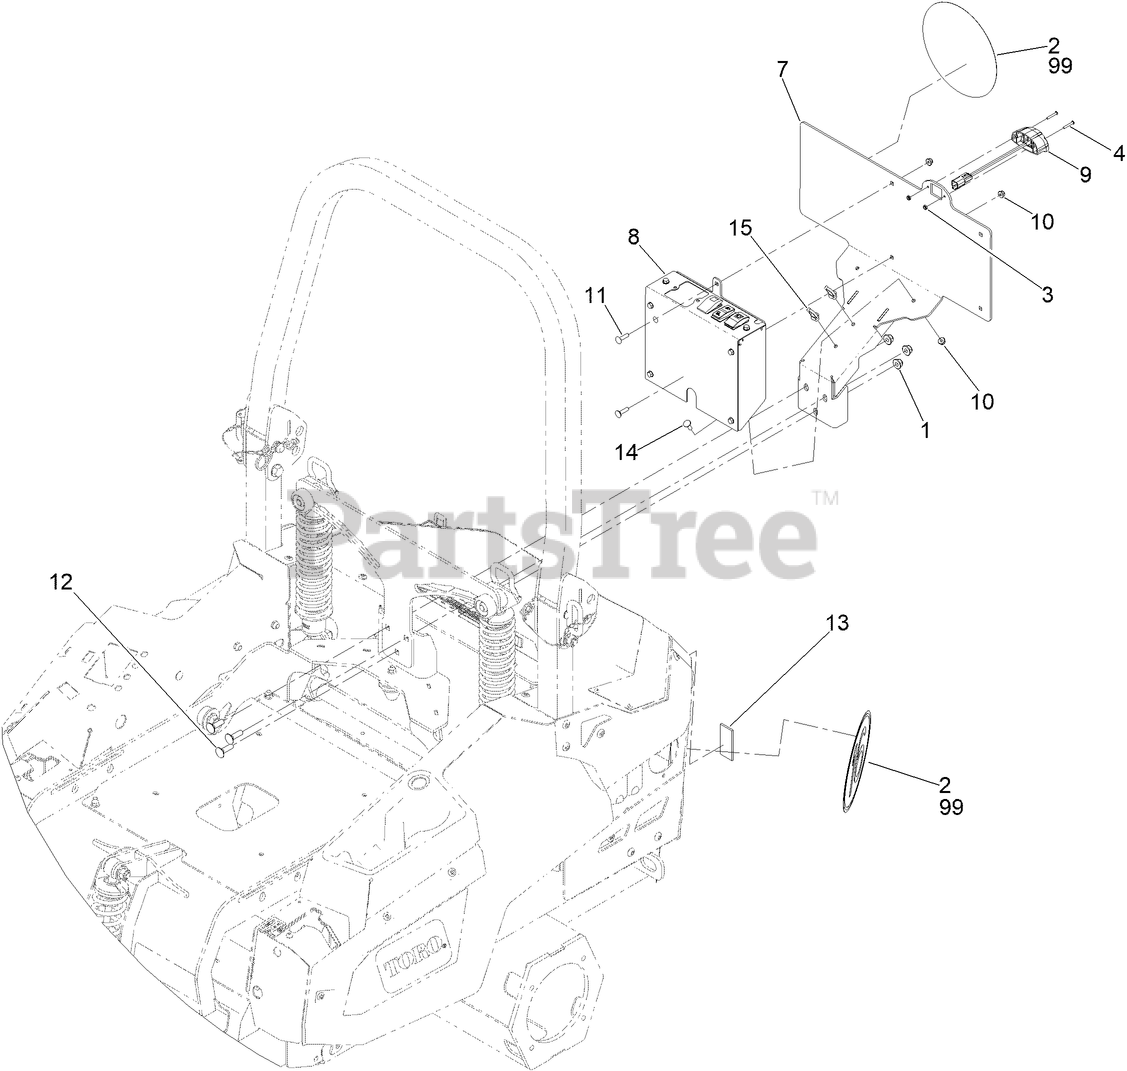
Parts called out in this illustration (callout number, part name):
1	NUT-HF, NI
2	SIGN-PVC
3	NUT-LOCK
4	SCREW-PPH
7	LICENSE-PLATE MOUNT ASM [BLACK]
8	CONTROL-LIGHTS, ASM
9	LIGHT-PLATE, LICENSE (ECE)
10	NUT-HF
11	BOLT-CARRIAGE
12	BOLT-CARR
13	REFLECTOR-ADHESIVE
14	BOLT-CARR
15	CLIP-TIE
99	DECAL-SPEED, 10 KPH
